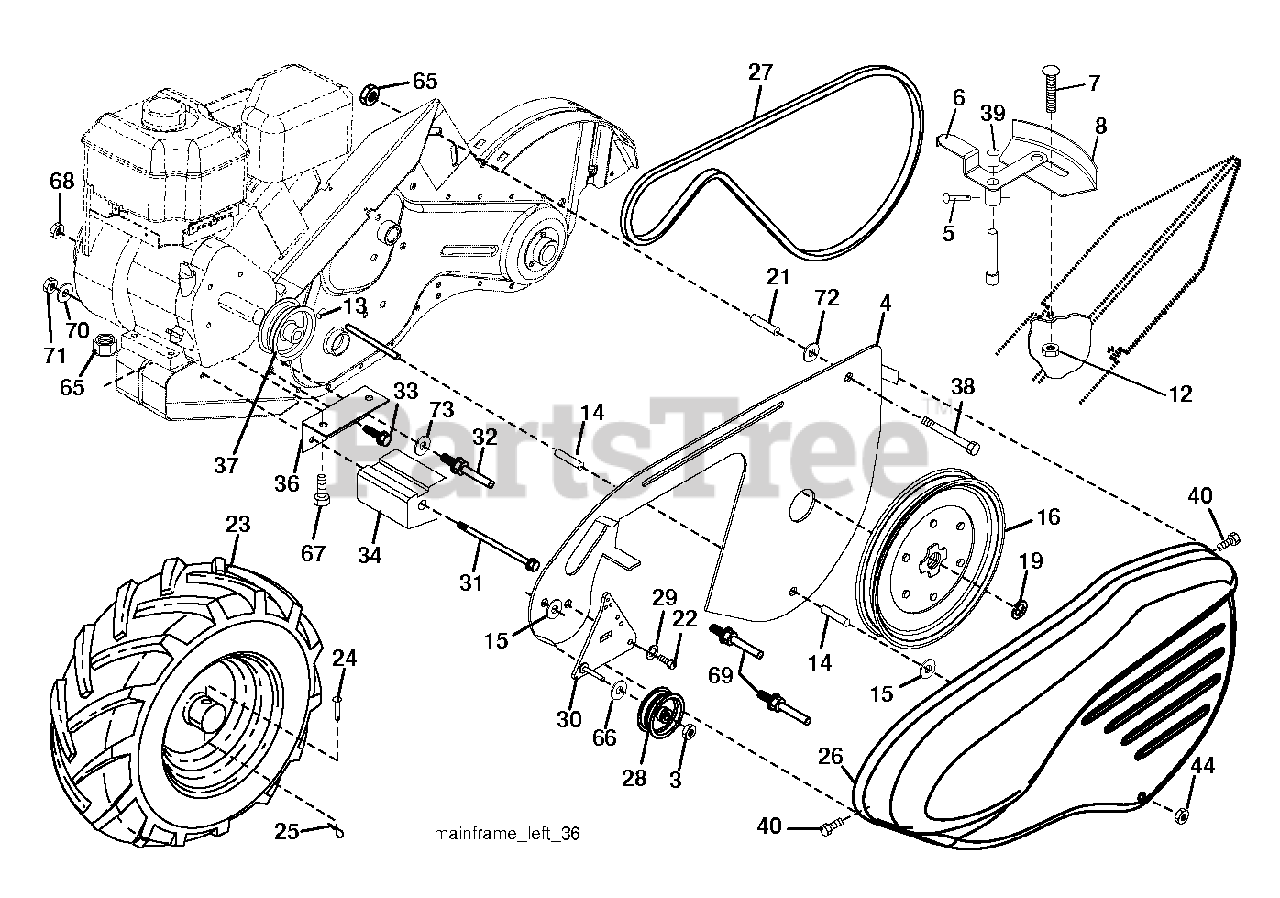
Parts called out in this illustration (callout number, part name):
3	LOCKNUT
4	SHIELD.INNER.BELT.GUARD.RT.BLA
5	PIN.SPIROL.FLARED
6	LEVER.ASM.SHIFT.RED
8	PANEL.INDICATOR.SHIFT.BLACK.
12	NUT
14	SPACER-SPLIT.327 X .42
15	WASHER.FLAT.34X1.38X22
16	SHEAVE, TRANSMISSION
19	RETAINING RING LT
21	SPACER SPLIT
23	WHEEL.ASM.DRT.13X5-6.LT.SILVER
24	RIVET
25	RETAINER M
26	GUARD.BELT.TILLER.ORANGE
27	V-BELT
28	PULLEY-IDLER TI
30	BRACKET.IDLER.ASM.LONG
31	BOLT.FIN.HEX.3/8-16UNC X 11.5
32	SHIFT ARM CRT
33	BOLT
34	COUNTERWEIGHT.LH
36	BRACKET.REINFORCEMENT.LH.PNT
37	ENGINE PULLEY
38	BOLT
39	CAP.PLUNGER.BLACK
40	SCREW.HEX.WSH.SLT.#10-24X.50
44	NUT.71038.31-18.HEX.NYLOCK
65	LOCKNUT-FLANGE 5/16-18
66	WASHER
67	BOLT, HEX 5/16-18X1-3/4
69	KEEPER.BELT.ENGINE
70	WASHER
72	SPACER (2 2MC)
73	WASHER
